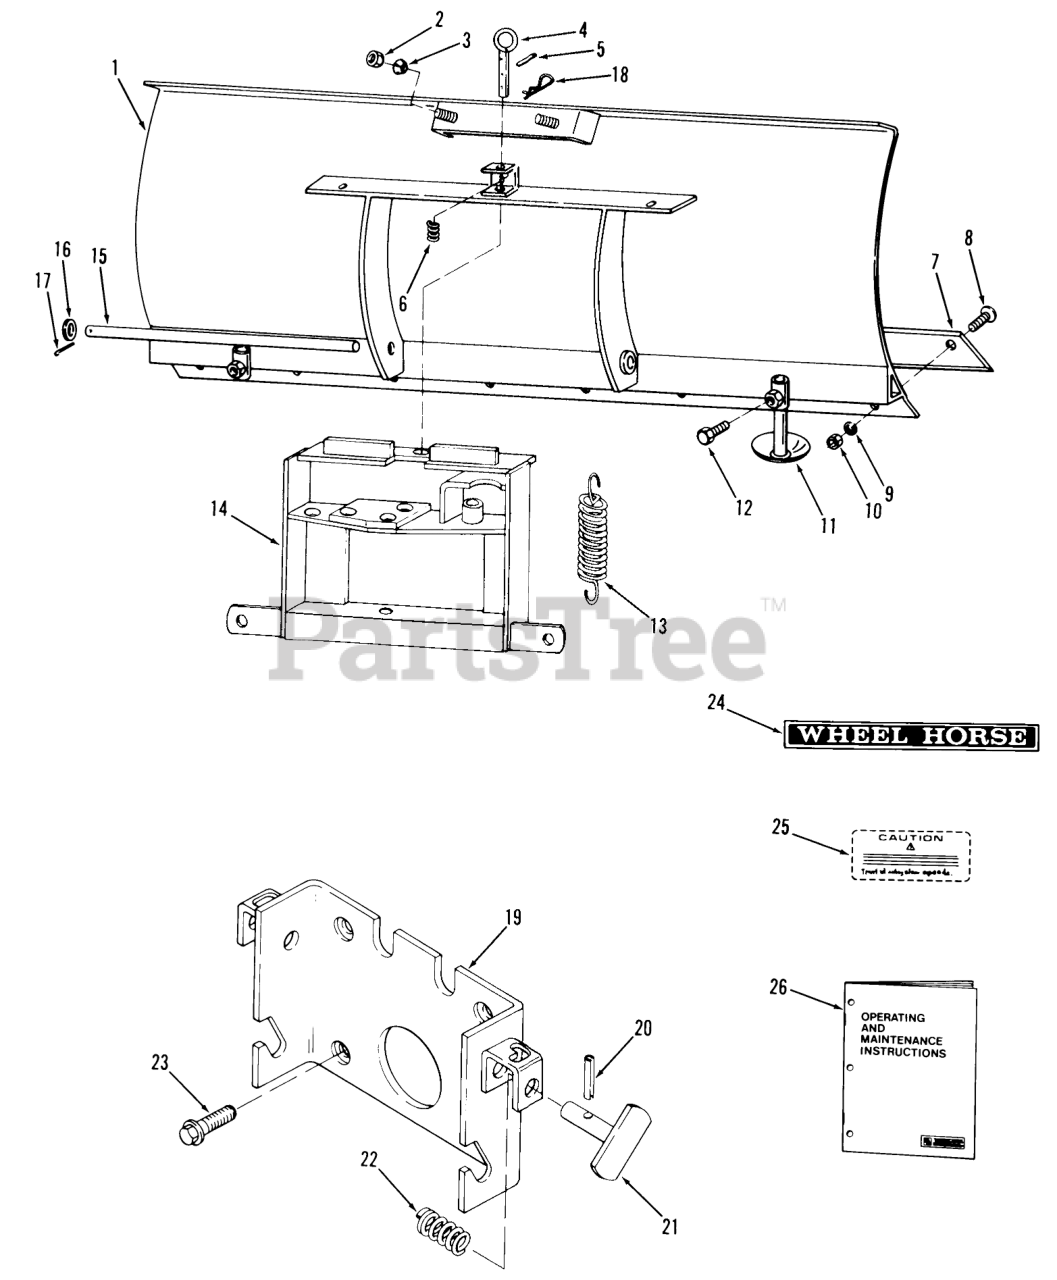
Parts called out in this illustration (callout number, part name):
1	Blade
3	Spring Lockasher
4	Trip Spring Lockout Pin
5	Rollpin
6	Spring
7	Scraper Blade
9	Lockwasher
13	Trip Spring
14	Indexing Bracket
15	Mounting Rod
17	Washer
18	Hairpin Cotter
19	Mounting Plate
20	Rollpin
21	Locking Pin
22	Spring
24	Decal
25	Caution Decal
26	Operating and Maintenance Instructions
